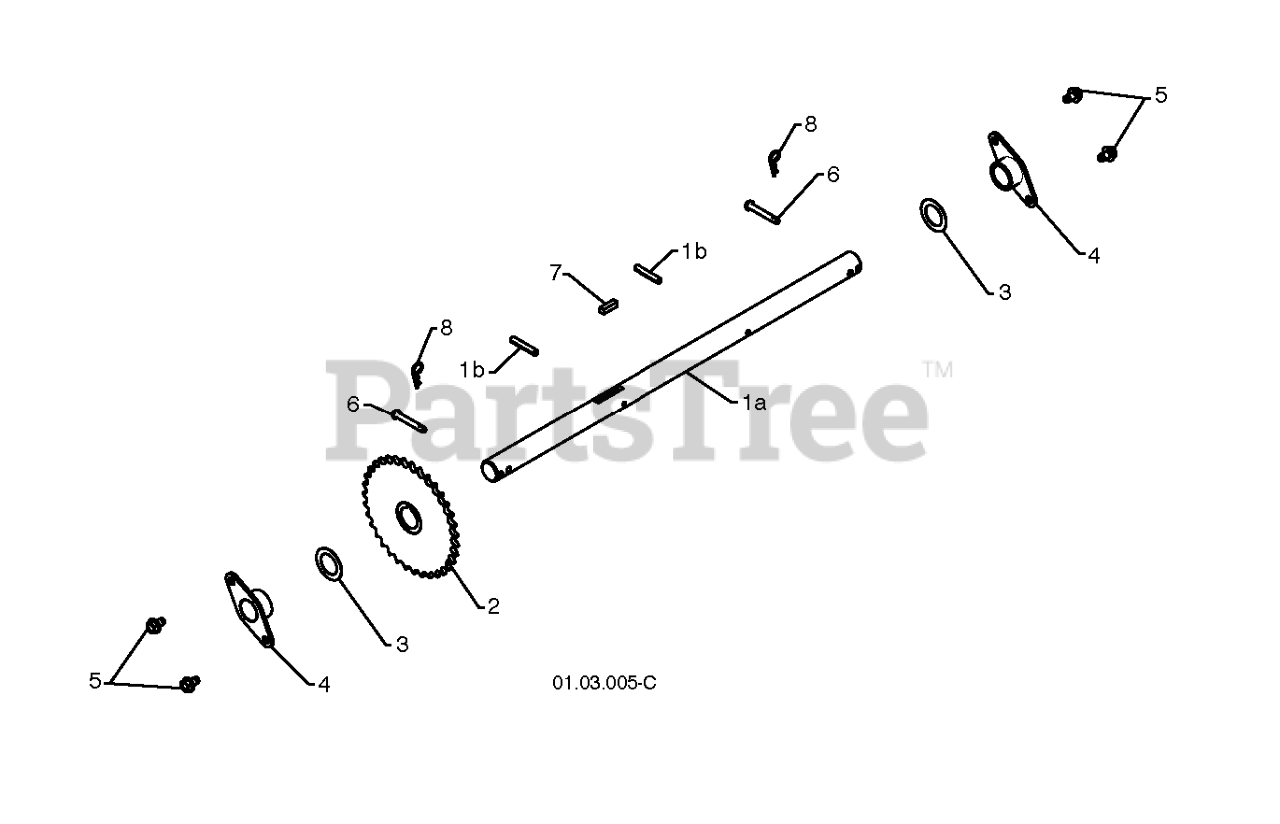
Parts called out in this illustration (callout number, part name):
1	AXLE.SHAFT.ASM.W/ROLPIN.NON-PS
2	SPROCKET.WELDMENT.AXLE.1.00
3	WASHER TRUST 1"
4	BEARING, AXLE
5	Screw 5/16-18 x 1/2 Hex, Self Tapping 5/16-18 x 1/2
6	RIVET
7	KEY, SQUARE 1/4 X .875
8	RETAINER M
